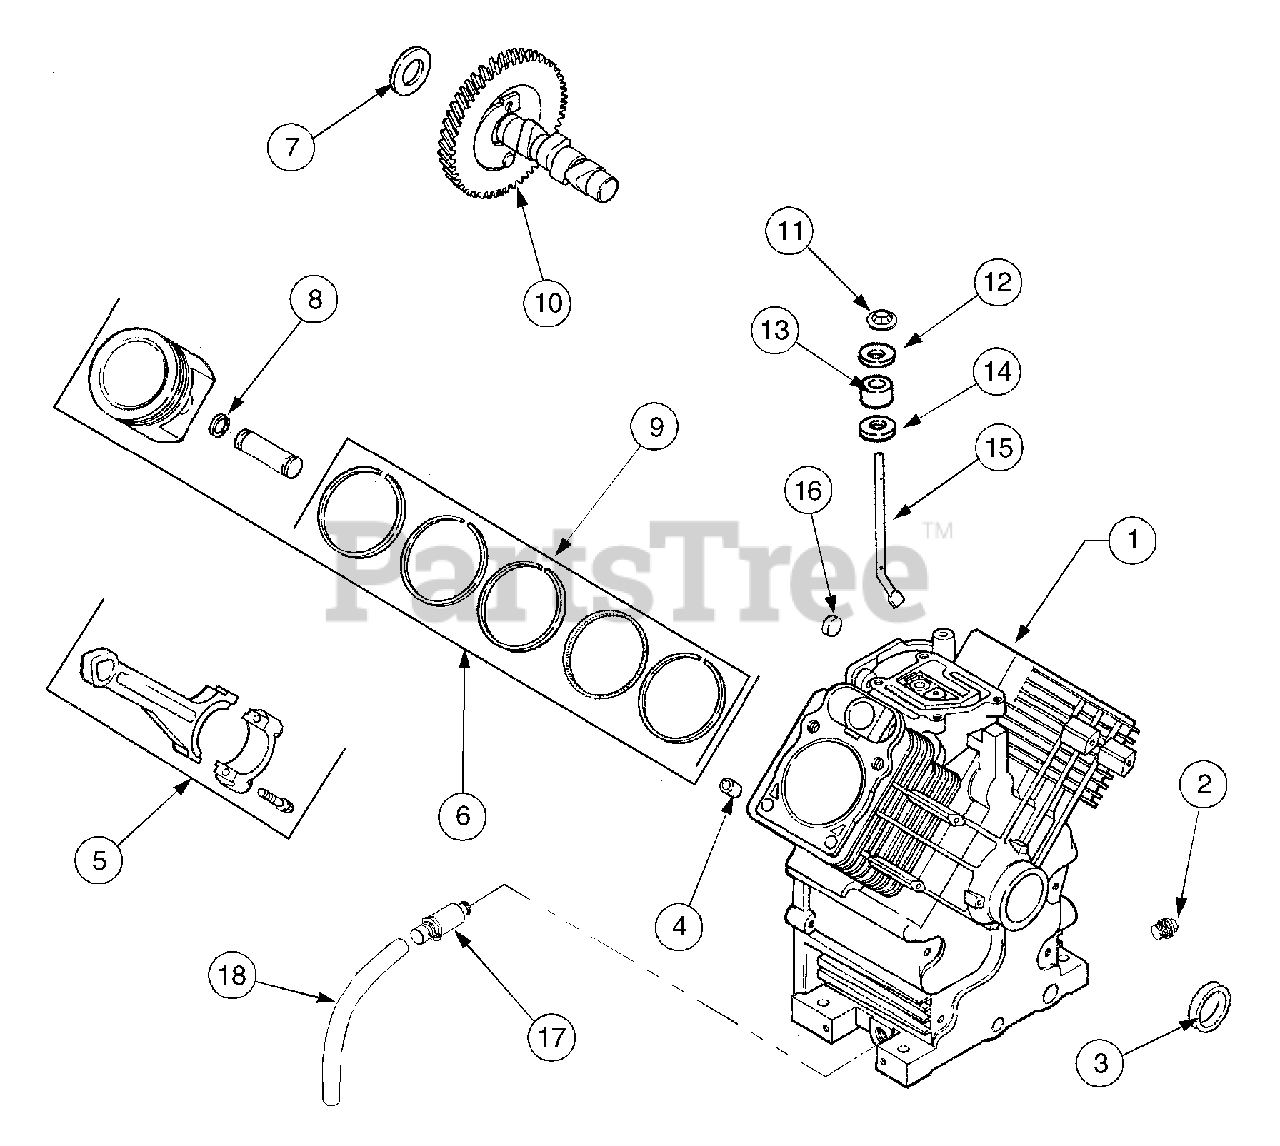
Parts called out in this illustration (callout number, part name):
1	Crankcase, (Use Miniblock)
2	Plug, Hex Hd, 3/8
3	Seal, Front Oil
4	Pin, Locating Dowel
5	Rod, Connecting, Std
5	Rod, Connection, .010 / .25mm
6	Piston w/Ring Set, Std
6	Piston w/Ring Set, .010 / .25mm
6	Piston w/Ring Set, .020 / .50mm
6	Piston w/Ring Set, .08mm
7	Shim, Camshaft, .0320 (Red)
7	Shim, Camshaft, .0400 (Black)
7	Shim, Camshaft, .0280 (White)
7	Shim, Camshaft, .0300 (Blue)
7	Shim, Camshaft, .0340 (Yellow)
7	Shim, Camshaft, .0360 (Green)
7	Shim, Camshaft, .0380 (Gray)
8	Retainer, Piston Pin
9	Ring Set, Std., .08
9	Ring Set, .010/ 2.5mm
9	Ring Set, .020/ 5.0mm
10	Camshaft Assembly
11	Ring, Retainer
12	Washer, Nylon
13	Seal, Governor Cross Shaft
14	Washer, Plain
15	Shaft, Governor Cross
16	Plug, Cup
17	Drain, Oil
18	Hose, Oil Drain
